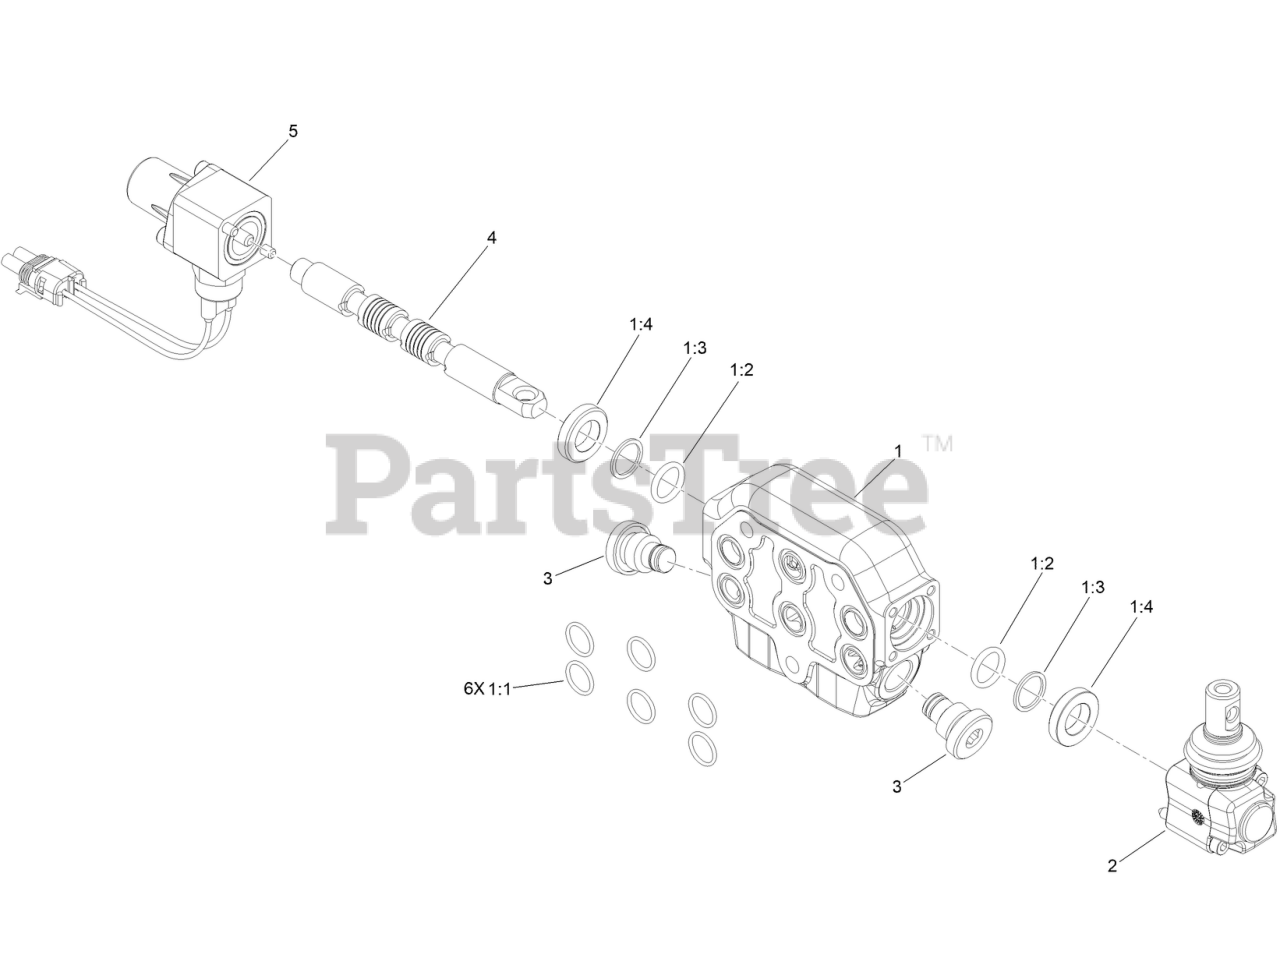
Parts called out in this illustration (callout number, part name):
1	SECTION-WORKING
1:1	O-RING
1:2	SEAL-VALVE
1:3	SEAL-VALVE
1:4	SEAL-VALVE
2	LEVER-VALVE
4	VALVE-SPOOL
5	KIT-CONTROL
